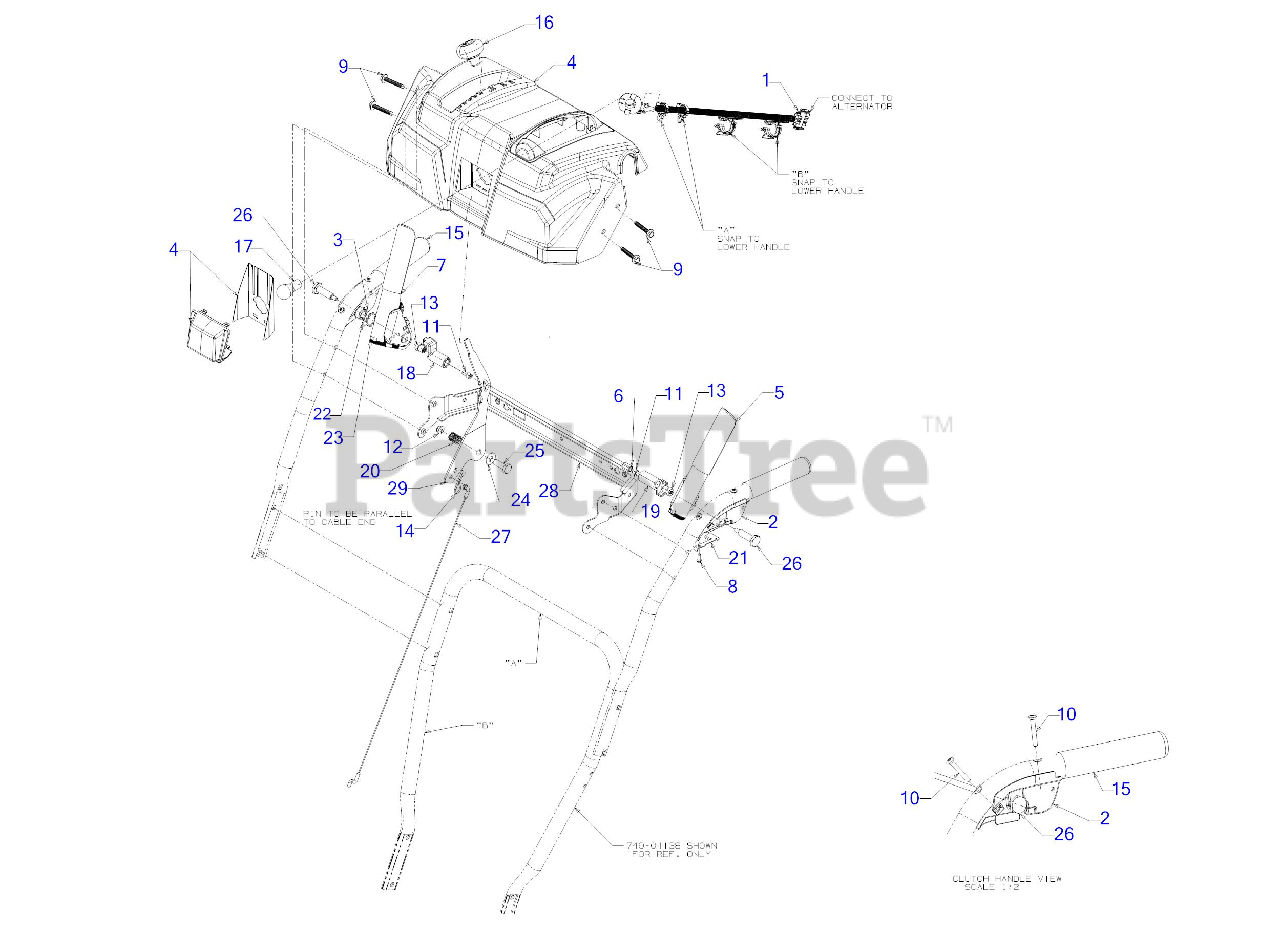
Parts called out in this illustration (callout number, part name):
1	LIGHT HARNESS
2	CLUTCH LOCK HANDLE ASSEMBLY (LH)
3	CLUTCH LOCK HANDLE ASSEMBLY (RH)
4	HANDLE PANEL ASSEMBLY (TROY-BILT)
5	HANDLE ASSEMBLY (LH)
7	HANDLE ASSEMBLY (RH)
8	SCREW #8-16 x .50
9	SCREW 1/4-20 x 1.625
10	SCREW #10-24 x 1.375
11	SCREW 1/4-20 x .50
12	FLANGE LOCK NUT
13	HEX NUT W/PATCH
14	INTERNAL COTTER PIN
16	SHIFT KNOB
19	CLUTCH LOCK CAM
20	COMPRESSION SPRING
21	CLUTCH SPRING
22	TORSION SPRING
23	RUBBER BUMPER
24	FLAT WASHER
25	SHOULDER SCREW
26	SHOULDER SCREW .437 x 1.345 1/4-20
27	SPEED SELECTOR CABLE (PLASTIC)
28	HANDLE SUPPORT BRACKET
